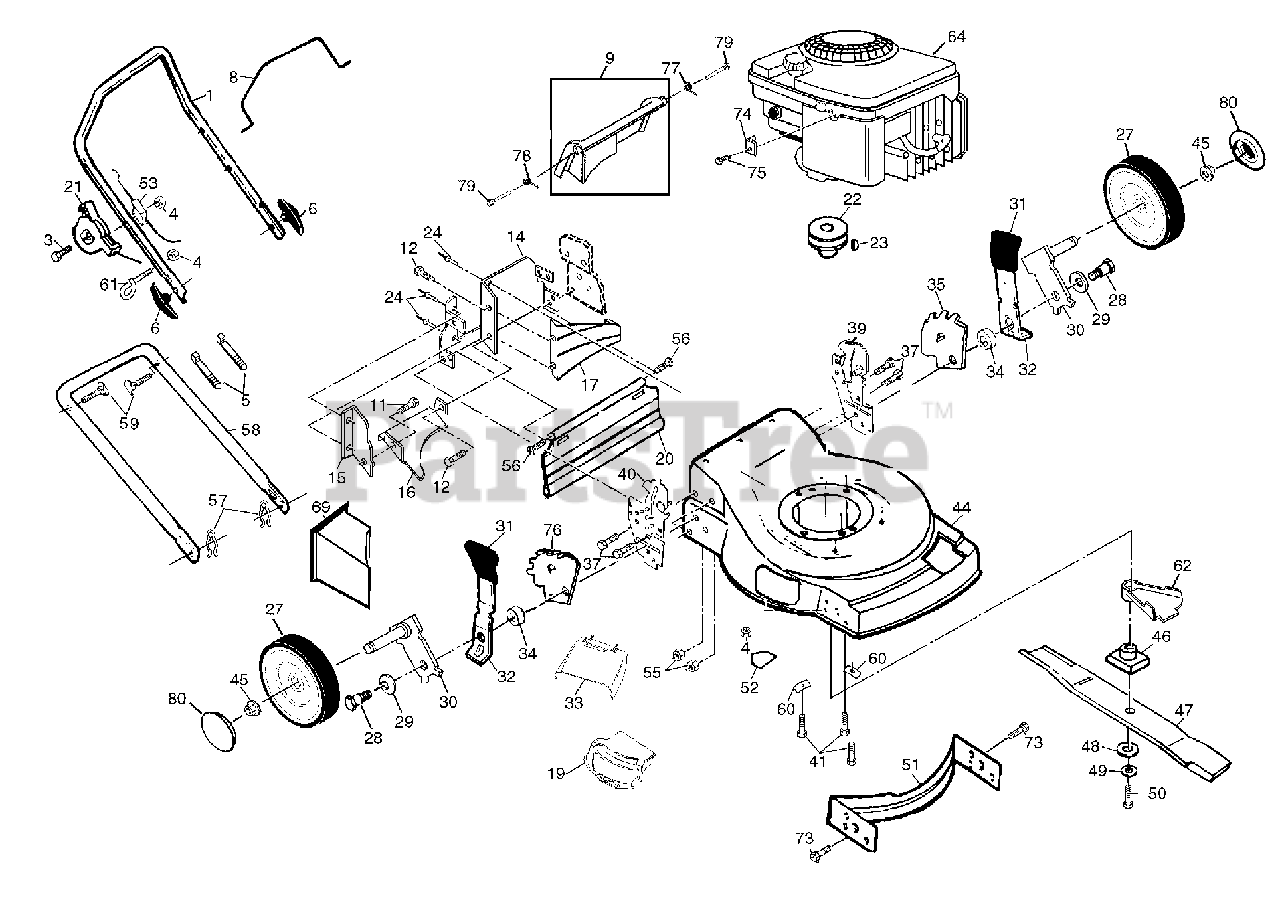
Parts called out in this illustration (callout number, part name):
1	Upper Handle
3	Hex Washer Head Screw 1/4-20 x 2-1/8
4	Locknut 1/4-20
5	Wire Tie
6	Handle Knob
8	Control Bar
9	Rear Door Kit
11	Self Tapping Screw #10-24 x 5/8
12	Hex Tapping Screw w/Sems 1/4-20 x 1/2
16	Discharge Baffle
17	Rear Baffle
19	Combi-cut Door
20	Rear Skirt
21	Throttle Control
22	Engine Pulley
23	Hi-Pro Key #505
24	Pop Rivet
27	Wheel
28	Shoulder Bolt 3/8-16 x 1-3/8
29	Spring Washer
30	Axle Arm Assembly
31	Selector Knob
32	Selector Spring
33	Clip-on Discharge Deflector
34	Spacer
35	Wheel Adjusting Bracket
37	Thread Cutting Screw w/Sems 5/16-18 x 3/4
39	Handle Bracket Assembly (Left)
40	Handle Bracket Assembly (Right)
41	Hex Head Thread Rolling Screw 3/8-16 x 1-1/8
44	Lawn Mower Housing
45	Flanged Locknut 3/8-16
46	Blade Adapter
47	Blade 22"
48	Hardened Washer
49	Helical Washer
50	Hex Head Machine Screw 3/8-24 x 1-3/8 Gr.
51	Front Baffle Kit
52	Danger Decal
53	Cable
55	Locknut 3/8-16
56	Hinge Screw 1/4-20 x 1-1/4
57	Hairpin Cotter
58	Lower Handle
59	Handle Bolt
61	Rope Guide
62	Debris Shield
69	Mulcher Plug
73	Screw Hx Serrated 1/4 x 20.TT
74	Clamp
75	Screw
76	Wheel Adj. Brkt RH
77	Spring LH
78	Spring RH
79	Bolt
80	Hubcap
80	Operator's Manual (English)
